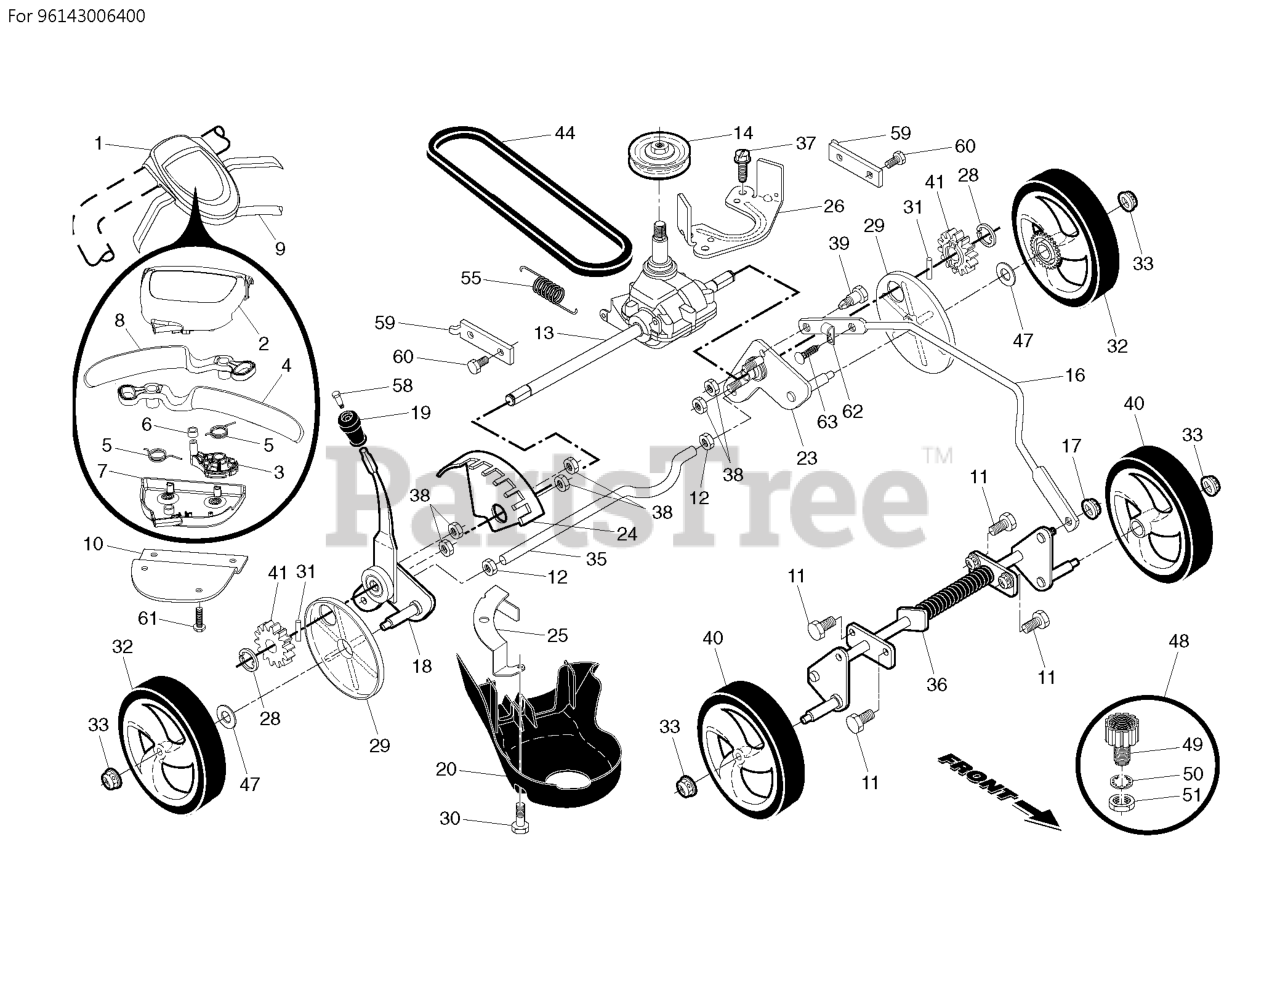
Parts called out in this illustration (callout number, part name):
1	RB CTRL.AW2.22+RGD.BS.GRY/BLK
2	RP CASE.CONT.ROL.TOP.HUSQV.
3	CAM.GEN2.DUAL.TRIGGER
4	LEVER.CONTROL.LH.22+.CURVE.BLA
5	SPRING, DRIVE CONTROL
6	BUSHING.CONTROL.CAM
7	COVER.DR.CONTROL.LOWER.GRAY
8	LEVER.CONTROL.RH.22+.CURV.BLAC
9	CABLE.CONTROL.22RGD.GEN2
10	BRACKET.DRIVE.CONTR.GEN2.BLACK
13	TRANMISSION.22+.RGD.AW
16	KNOB.SEL.SPRING.22+.SP.RIB.BLK
17	NUT.LOCK.5/16-18
18	SELECTOR.ASM.22+.RT.SPT LW RGD
19	KNOB.SEL.SPRING.22+.SP.RIB.BLK
20	COVER.BELT.22.RGD
23	Wheel Axle Assembly, LH
24	BRACKET.WHL.ADJ.9.POS.W/PAD
25	BRACKET.DRIVE.COVER.RGD.BZP
26	BRACKET.TRANS.BELT.KEEPER.BZP
28	E-RING 7/16 RE
29	COVER.DUST.WHEEL
30	BOLT.HEX.HD.WASHER.5/16-18X.75
31	PAWL, DRIVE
32	WHEEL & TIRE ASSY, REAR
33	NUT.HEX.FLANGE.3/8-16.LO(3 2)
35	AXLE.REAR.RGD
36	AXLE.ASM.FRONT.RGD.BZP
38	NUT.HEX.FLANGE.1/4
39	SHOULDER BOLT SEMI GIMLET PT.
40	WHEEL & TIRES ASSY, FRONT
41	PINIION.14.TOOTH.RGD
44	BELT.DRIVE.RGD.PLUS
47	WASHER FLUT
48	KIT.WASH-OUT.PORT
49	FITTING, HOSE, WATER WASHOUT
50	WASHER.LOCK.INTERNAL.TOOTH
51	LOCKNUT.HEX.WITH.O-RING
58	BOLT.HEX.HD.WASHER.5/16-18X.75
59	BRACKET.SUPPORT.22+.RWGD.BZP
60	BOLT.HEX.HD.WASHER.5/16-18X.75
61	SCREW, PHILLIPS HEAD 10 X 5/8
62	CLIP.CABLE.BLK
63	FASTENER.PUSH.O.250X0.783
